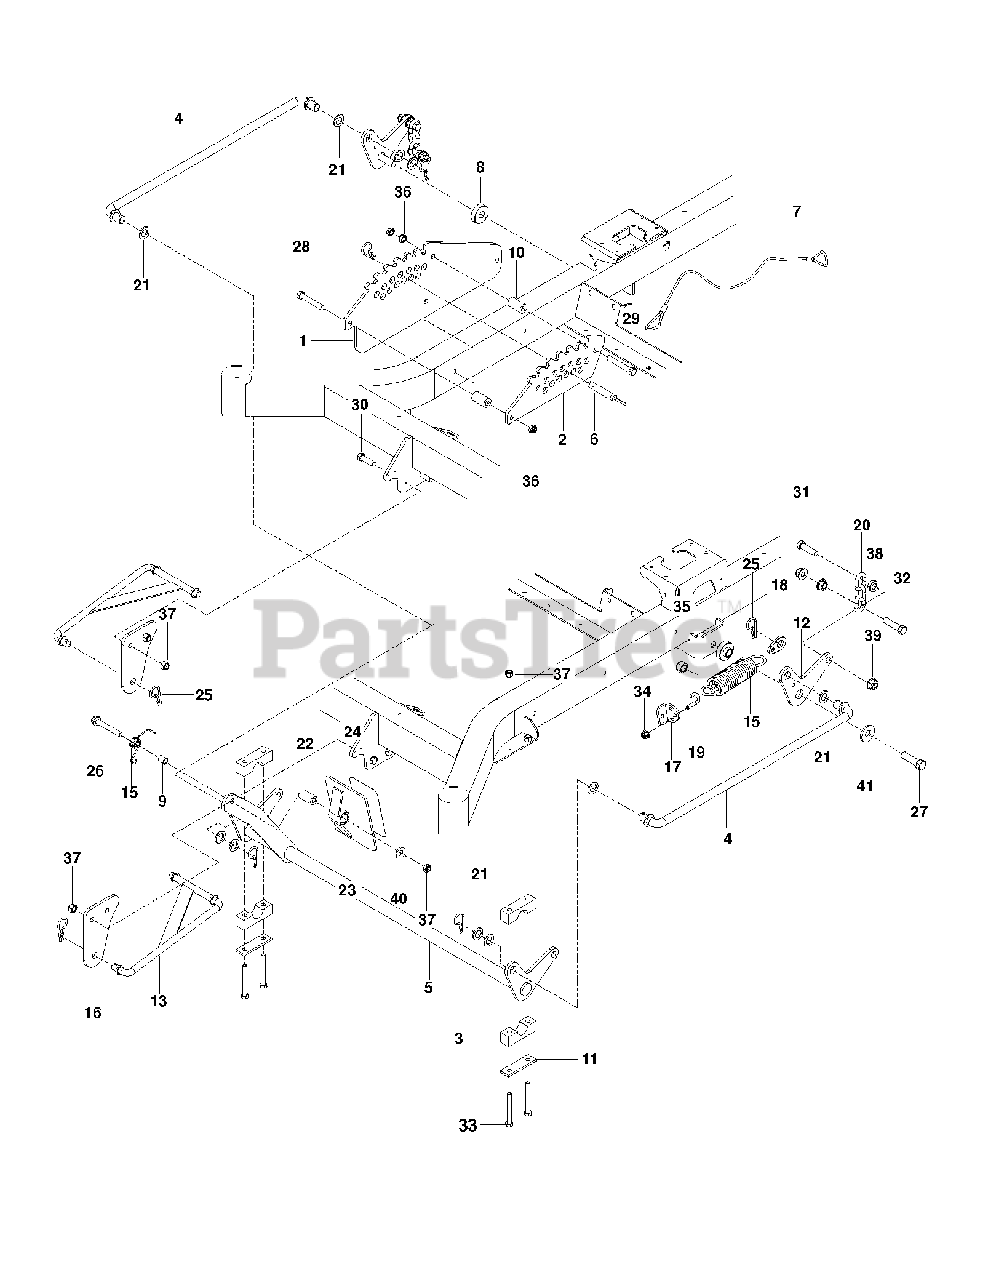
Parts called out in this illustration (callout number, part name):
3	PILLOW BLOCK
4	CROSS LINK
5	SHAFT, LIFT, DECK
6	HITCH PIN
7	LANYARD
8	IDLER SPACER
10	DECK LIFT SPACER
11	REINFORCEMENT BAR
12	BELLCRANK, REAR LIFT
13	STRUT LINKAGE
14	SPRING, TORSION
16	MOUNT, STRUT
17	MOUNT, SPRING
18	TAB, SPRING
20	LIFT CHAIN - 3 LINK
21	BUSHING
22	BUSHING, SLEEVE
23	PEDAL, FOOT, WELDMENT
24	FOOT PAD
25	PIN, COTTER 1 3/4
26	HHFS 3/8-16 X 2 3/4
27	HCS 1/2-13 X 1 3/4 GR 8
28	HCS 3/8C X 2 1/4
29	HCS 3/8C X 2 1/2
30	HCS 3/8C X 1 1/4 GR5
31	HCS 7/16C X 1 1/2
32	HCS 7/16 - 14 X 1 3/4
33	HCS 5/16C X 2-3/4
34	5/16-18 NYLOC FLANGE NUT
35	NUT 1/2-13 HEX NYLOC ZD
36	NUT HEX 3/8-16 NYLON, THIN
37	NUT 3/8-16 NYLOC
38	NUT 7/16C WHIZ
39	NUT 7/16-14 HEX WHIZ LK
40	WASHER 3/8 FLAT
41	WASH USS FLAT 1/2
